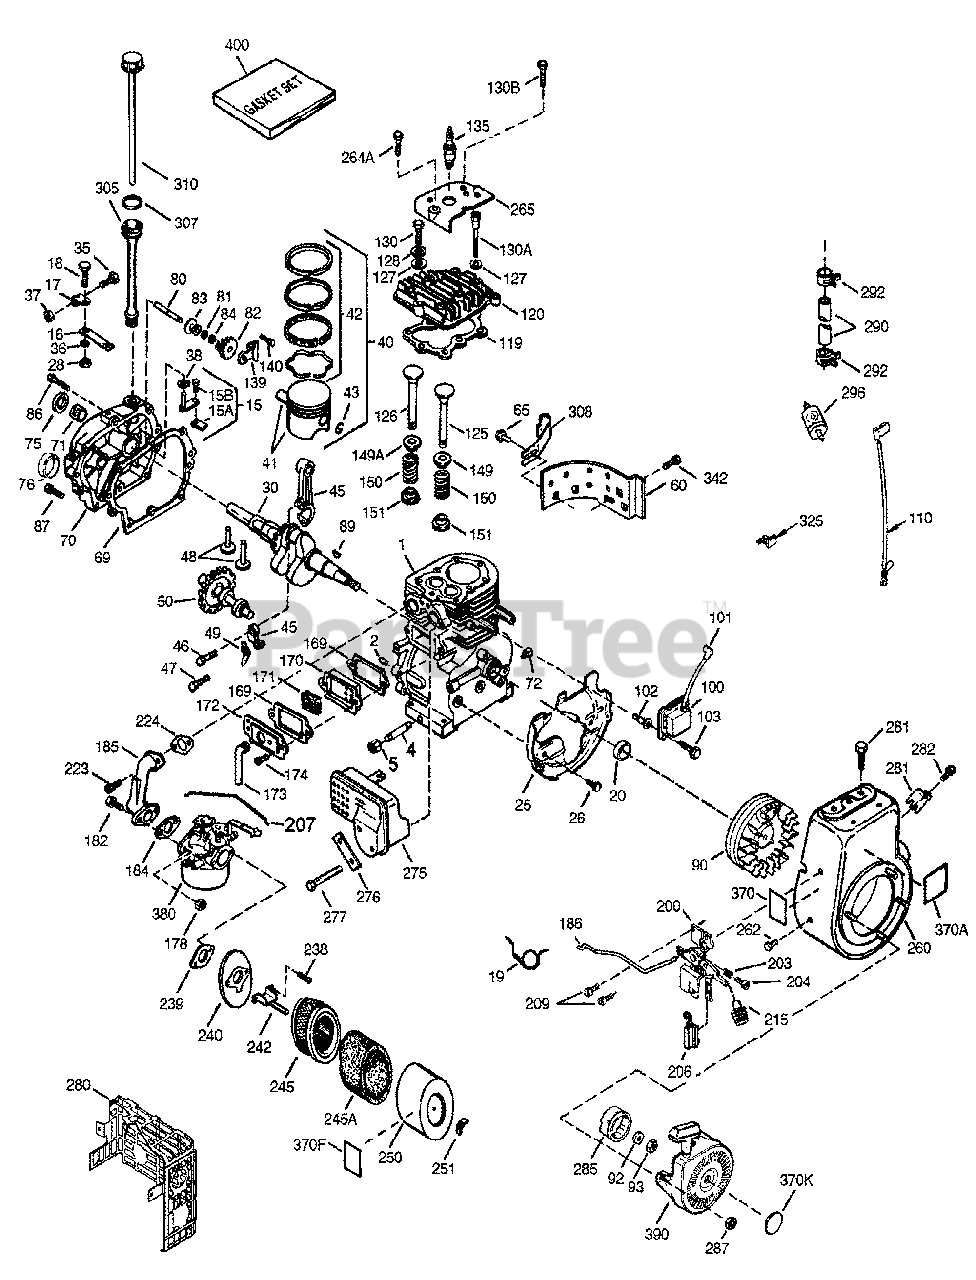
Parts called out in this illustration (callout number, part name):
1	Cylinder
2	Dowel Pin
4	Oil Drain Extension
5	Extension Cap
15	Governor Rod
15A	Governor Yoke
15B	Screw, 6-40 x 5/16"
16	Governor Lever
17	Governor Lever Clamp
18	Screw, 8-32 x 5/16"
19	Speed Control Spring
25	Blower Housing Baffle
26	Screw, 1/4-20 x 5/8"
28	Lock Nut, 3-32
30	Crankshaft
35	Screw, 10-32 x 3/4"
36	Lock Washer
37	Lock Nut, 10-32
38	Retaining Ring
40	Piston, Pin & Ring Set (Standard)
41	Piston & Pin Ass'y (Standard)
42	Ring Set (Standard)
43	Piston Pin Retaining Ring
45	Connecting Rod Ass'y
46	Connecting Rod Bolt
47	Connecting Rod Bolt
48	Valve Lifter
49	Oil Dipper
60	Blower Housing Extension
65	Screw, 10-24 x 1/2"
69	Cylinder Cover Gasket
70	Cylinder Cover
71	Crankshaft Bushing
72	Oil Drain Plug
76	Camshaft Seal
80	Governor Shaft
82	Governor Gear Ass'y
83	Governor Spool
84	UKNOWN
86	Screw, 1/4-20 x 1-1/4"
87	Screw, 1/4-20 x 1-11/16"
89	Flywheel Key
92	Lock Washer
93	Flywheel Nut
100	Solid State Ignition
101	Spark Plug Cover
102	Solid State Mounting Screw
103	Screw, Torx T-15, 10-24 x 15/16"
110	Ground Wire
119	Cylinder Head Gasket
120	Cylinder Head
125	Exhaust Valve (Standard)
126	Intake Valve (Standard)
128	Bell Washer
130	Screw, 5/16-18 x 1-1/2"
130A	Screw, 5/16-18 x 1-3/4"
130B	Screw, 1/4-20 x 5/8"
135	Resistor Spark Plug (J8C/356)
139	Governor Gear Bracket
140	Screw, 10-24 x 1/2"
149	Valve Spring Cap
149A	Valve Spring Cap
150	Valve Spring
151	Valve Spring Keeper
169	Valve Cover Gasket
170	Breather Body
171	Breather Element
172	Valve Cover
173	Breather Tube
174	Screw, 10-24 x 1/2"
178	Nut and Lock Washer, 1/4-28
182	Screw, 1/4-20 x 1"
184	Carb. to Intake Pipe Gasket
185	Intake Pipe
186	Governor Link
200	Control Bracket
203	Compression Spring
204	Screw, 5-40 x 7/16"
207	Throttle Link
209	Screw, 10-32 x 1/2"
215	Control Knob
223	Screw, Torx T-30, 5/16 -18 x 1-1/8"
224	Intake Pipe Gasket
238	Screw, 10-32 x 1/2"
239	Air Cleaner Gasket
240	Air Cleaner Body
242	UKNOWN
245	Air Cleaner Filter
245A	Air Cleaner Filter (Poly)
250	Air Cleaner Cover
251	Wing Nut, 1/4-20
260	Blower Housing
261	Screw, 5/16-18 x 3/4"
262	Screw, Torx T-40, 5/16-24 x 21/32"
264A	Screw, 1/4-20 x 5/8"
265	Cylinder Head Cover
276	Locking Plate
277	Screw, 5/16-18 x 3-3/16"
280	Heat Shield
281	Starter Bubble Cover
282	Screw, 8-32 x 3/8"
285	Starter Cup
287	Nut & Lock Washer, 1/4-28
290	Fuel Line
292	Fuel Line Clamp
296	Fuel Filter
305	Oil Fill Tube
308	Fill Tube Clip
325	Wire Clip
342	Screw, Torx T-30, 1/4-20 x 1/2"
370	Instructional Decal
370A	Throttle Decal
370F	Instruction Decal
370K	Starter Decal
380	Carburetor
390	Rewind Starter
400	Gasket Set
